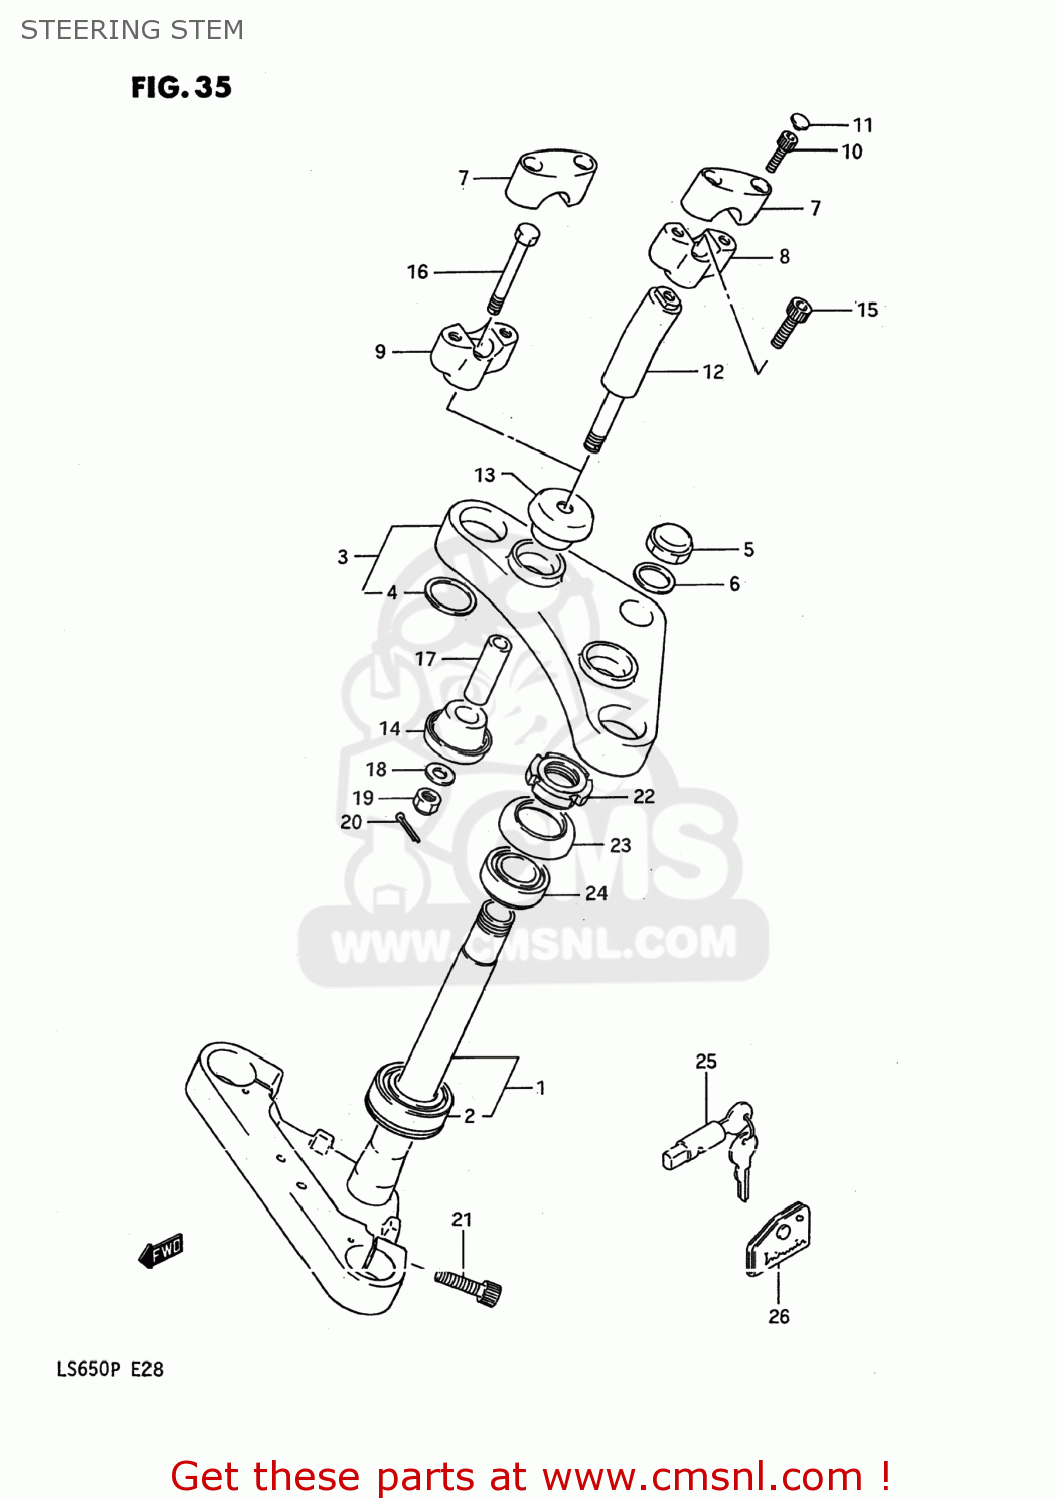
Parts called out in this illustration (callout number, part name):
1	STEM,STEERING
2	BEARING(30X55X17)
3	HEAD,STEERING STEM
4	WASHER,STEM HEAD,LOWER
5	NUT,CAP
6	WASHER(22.5X32X1.6)
7	HOLDER,HANDLE UPR
8	HOLDER,HANDLE LWR
9	HOLDER,HANDLE LWR
10	BOLT, LH
11	CAP(OD:14.5)
12	ARM
13	CUSHION,UPR
14	CUSHION,LWR
15	BOLT
16	BOLT,HANDLBAR CLAMP
17	SPACER(10.2X14X46)
18	WASHER 10MM
19	NUT
20	PIN 20X20
21	BOLT, (10X30)
22	NUT,STEERING STEM(25X44X10)
23	DUST SEAL,STEERING,UPPER
24	TAPER,ROLLER BEARING
25	LOCK ASSEMBLY,STEERING (NEI
26	CASE,STEERING KEY
